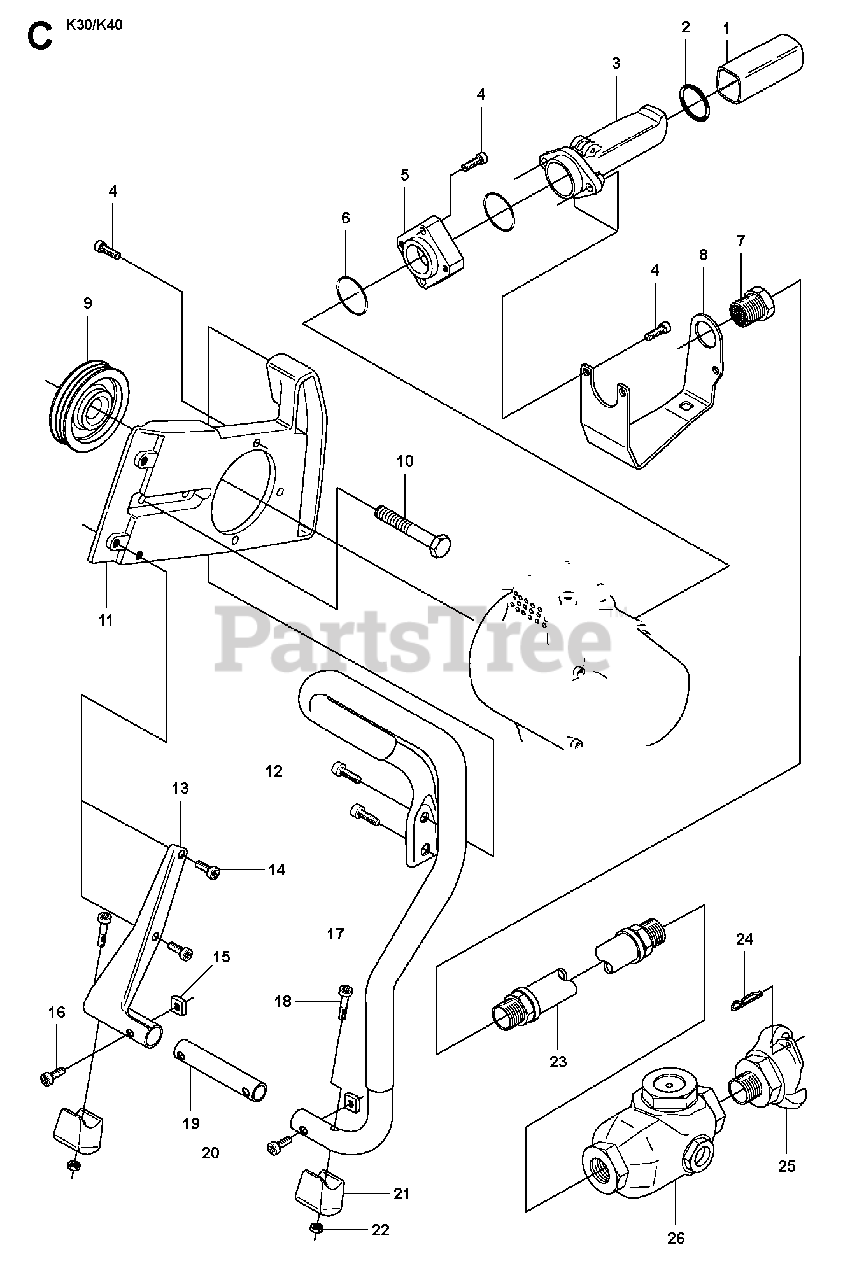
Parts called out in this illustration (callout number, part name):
4	SCREW ITXSCM
12	SCREW ITXSCM
14	SCREW ITXSCM
16	SCREW ITXSCM
18	SCREW ITXSCMK40
20	SCREW ITXSCM
21	GROUND SUPPORTK40
